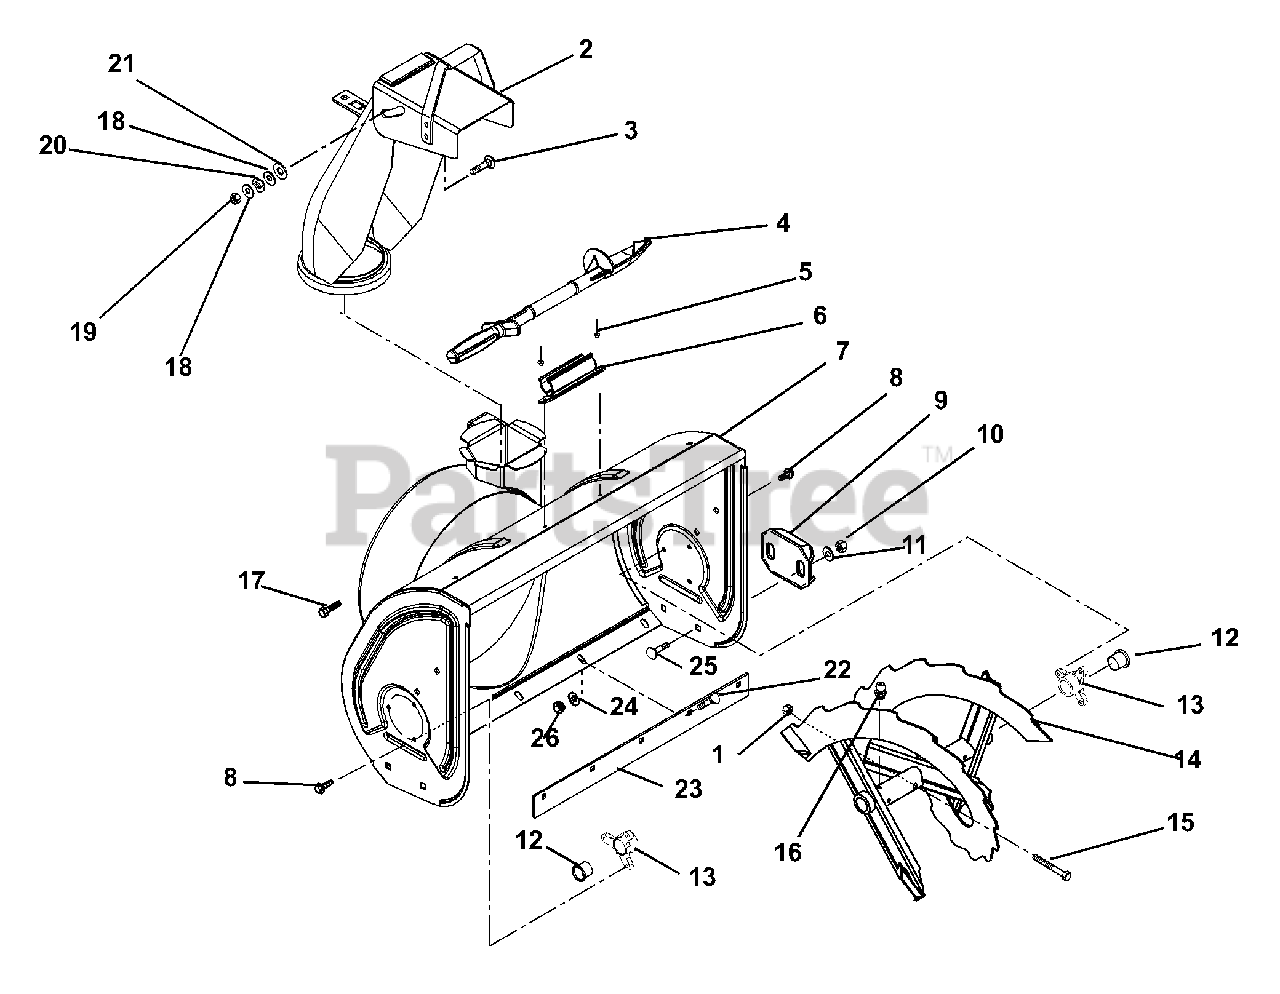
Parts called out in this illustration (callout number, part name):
1	@NUT-LK-CTR .25-20 YWZC
2	CHUTE, DISCHARGE W/CAP & DECAL
3	@BLT-RHDSSQNK .31-18X.75 G5YZ
4	DEVICE, SNOW CLEAN OUT
5	RVT-POP .187X.45 DOME SS FBF64
6	MOUNT, SNOW CLEAN OUT
7	BLOWER HOUSING, 20"
8	@SCR-TAP .25-20X.50 HWH TR YWZ
9	SKID SHOE, REVERSIBLE - ORANGE
10	@NUT-LK-CTR .38-16 YWZC
11	@WSHR-FL-STL.38X.875X.083 YWZC
12	BSHG-FLG, SPLIT NYLINER .75"ID
13	BUSHING, RAKE SHAFT .75"
14	AUGER, 20" RH, BLK SERR W/ZERK
15	SHEAR BOLT WITH NUT
16	ZERK,FITTING .25X.125 DRIVE IN
17	@SCR-TAP .38-16X.50 HWH TR YWZ
18	@WSHR-FL-STL.344X.688X.065YWZC
19	@NUT-LK-CTR .31-18 YWZC
20	WAVE WASHER .390X.655X.110
21	WSHR-PLASTIC .390X.875X.062
22	@BLT-RDHDSQNK .31-18X.50 G5YZ
23	BLADE, SCRAPER - 20" COMPACT
24	@WSHR-FL-STL.344X.688X.065YWZC
25	@BLT-RHDSSQNK .38-16X.75 G5YZ
26	@NUT-LK-CTR .31-18 YWZC
